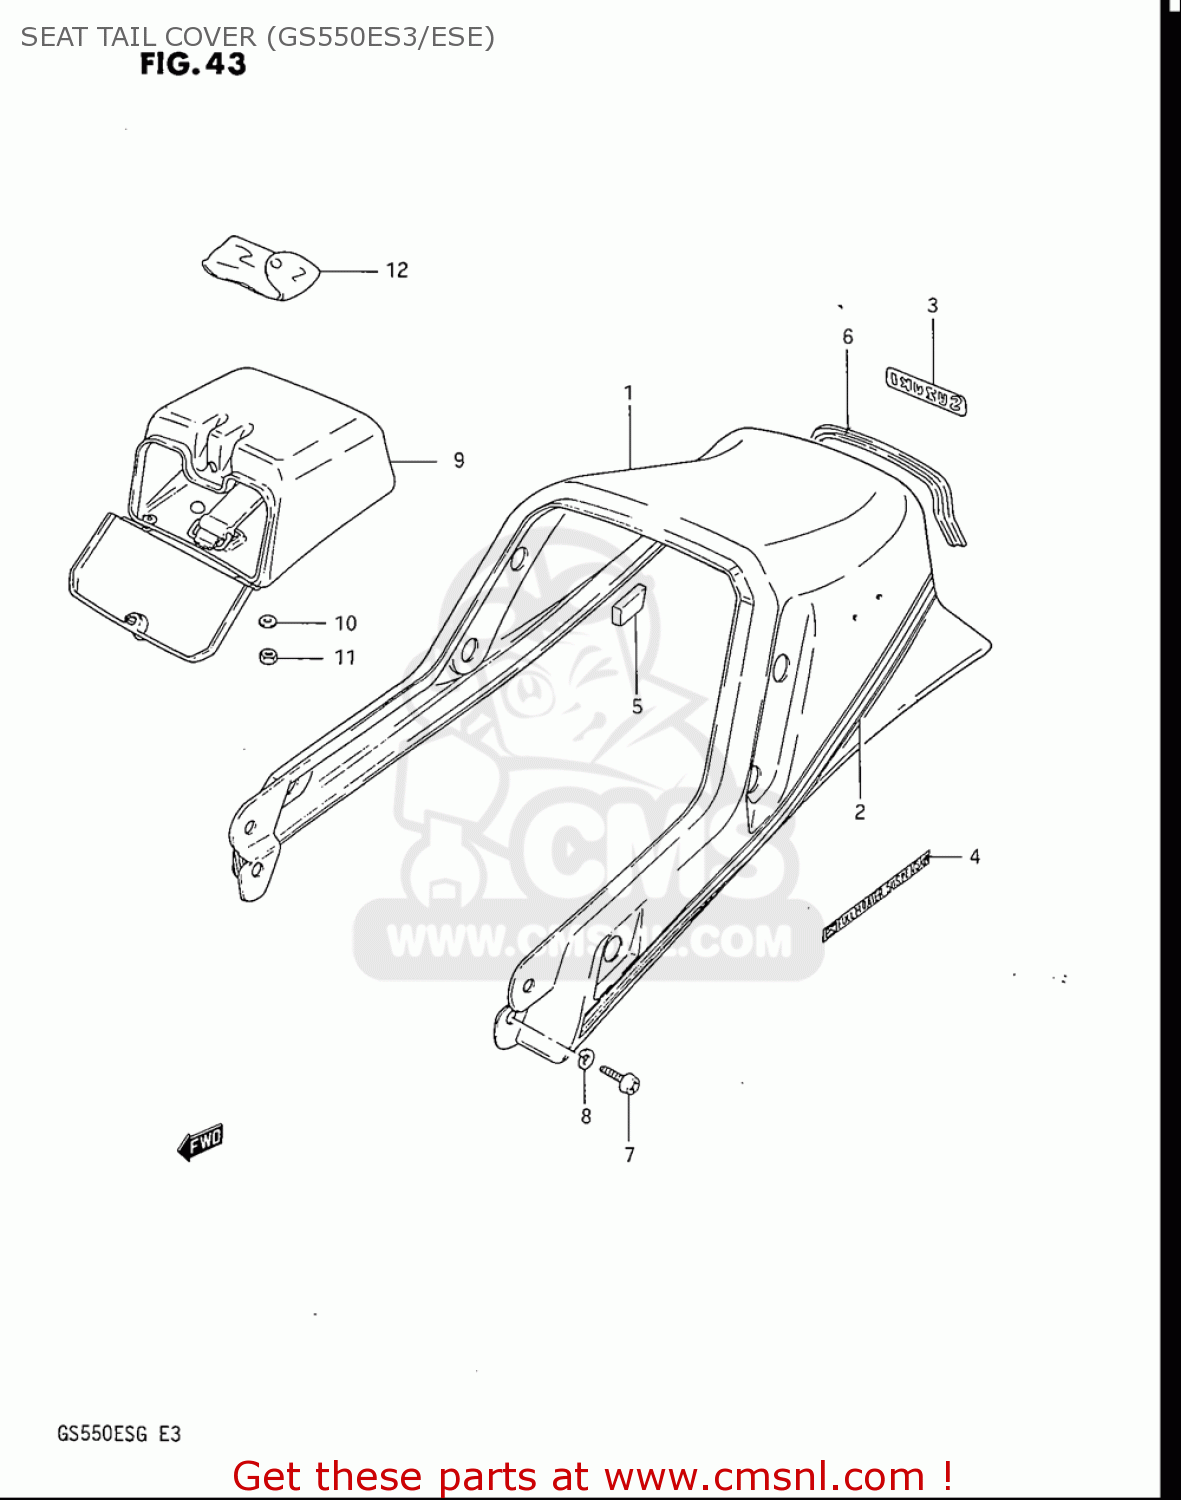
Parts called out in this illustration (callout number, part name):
1	COVER,SEAT TAIL
3	EMBLEM,LID FUEL TANK(BLACK)
4	EMBLEM
7	SCREW
8	WASHER,LOCK
10	WASHER
11	NUT
12	TOOL ASSY
